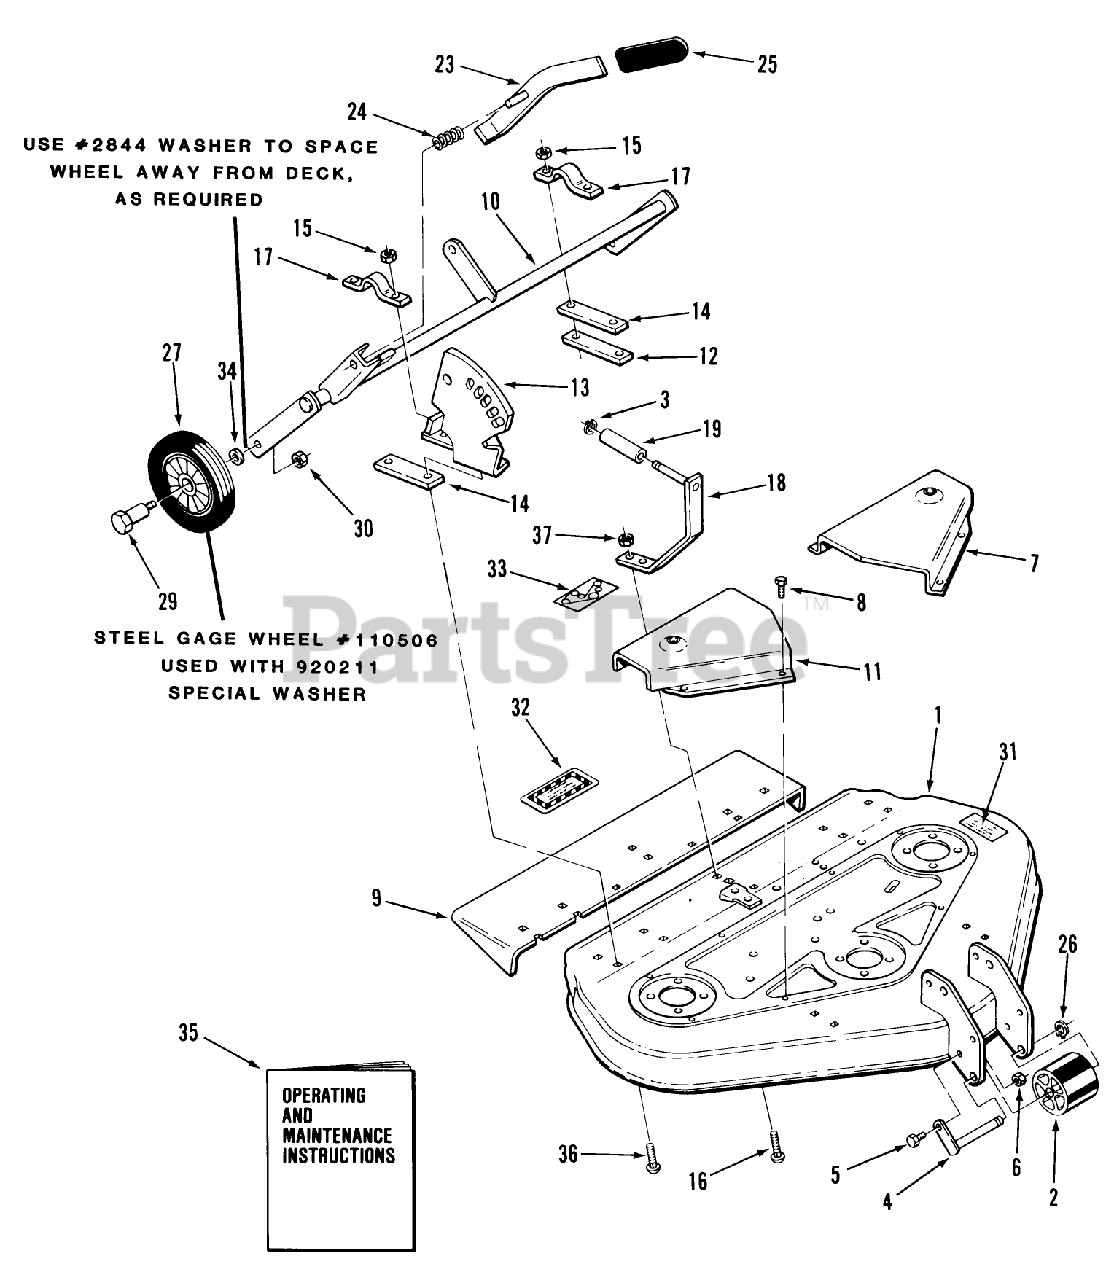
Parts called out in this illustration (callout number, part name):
8	Bolt
10	ASSY GAGE WHEEL S *R
24	SPRING-COMPRESSION
29	BOLT-SHOULDER
33	DECAL-HEIGHT BELT
34	WASHER-FLAT
35	Operating and Maintenance Instructions
